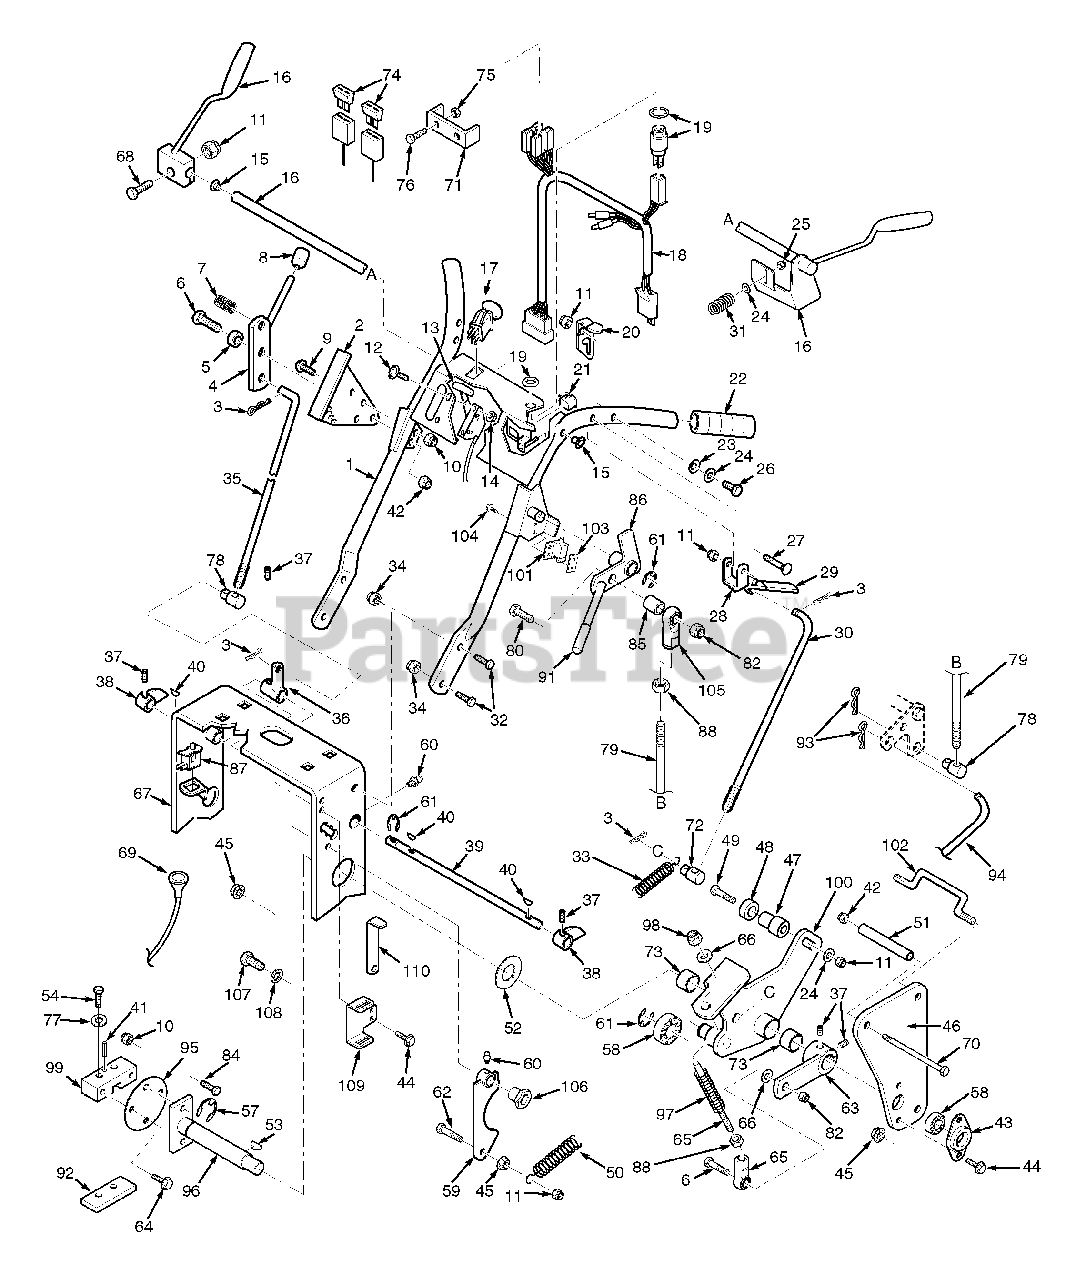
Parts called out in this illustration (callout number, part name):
1	Upper Handle Wlmt. W/Decals
2	Quadrant, Speed Control
3	Hairpin, .094 x 1.19
4	Lever, Speed Adjustment
5	Bushing, Speed Adjustment Lever
6	Hex Head Bolt, 3/8-16 x 1-1/2"
7	Ball Plunger
8	Knob, Speed Adjustment
9	Capscrew, 1/4-20 x 3/4" FHHS
10	Nut, 1/4-20 Elastic Stop
11	Nut, 5/16-18 Elastic Stop
12	Screw, #10-32 x 1/2" PW HD
13	Throttle Control
14	Nut, #10-32 Serr. Flange
15	Bushing
16	Handle, Oper. Presence-RH
17	Switch,Elec.Clutch Eng.
18	Wire Harness, Electric Start
19	Key Switch, Electric Srt.
20	Neutral Latch-RH
21	Switch, Neutral Interlock
22	Grip
23	Washer, Curved Spring
24	Flat Washer
25	Nut, 5/16-18 Elastic Stop
26	Hex Head Bolt, 5/16-18 x 2"
27	Hex Hd. Bolt, 5/16-18 x 2-1/2"
28	Lever, Steering Control
29	Grip, Steering Control
30	Rod, Steering Control
31	Spring, Handle Return
32	Capscr., 3/8-16 x 1" Ser. Flange
33	Spring
34	Nut, 3/8-16 Serr. Flange
35	Rod Speed Control
36	Bellcrank, Speed Control
37	Setscrew, 1/4-28 x .25"
38	Cam, Speed Control
39	Jackshaft, Speed Control
40	Key, 1/8 x 1/2" Woodruff
41	Roll Pin, 3/16-.75
42	Nut, Elastic Stop 3/8-16
43	Flange, Bearing
44	Capscrew, 5/16-18 x 1" Serr. Flg.
45	Nut, 5/16-18 Serrated Flange
46	Plate, Side
47	Spacer, Neutral Bearing
48	Bearing, Speed Ctrl. Bellcrank
49	Hex Head Bolt, 5/16-18 x 1-3/4"
50	Spring, Return
51	Spacer, Side Plate
52	Flat Washer, .766 x 1.25 x .035
53	Key, Woodruff, 3/16 x 3/4"
54	Bolt, Hex Head, 1/4-20 x 1-1/4"
55	Bolt, Hex Head, 5/16-18 x 3/4"
56	Lock Washer, 5/16"
57	Clip, Retaining, 3/4" diameter
58	Bearing, Ball Neutral Return
59	Cam, Neutral
60	Grease Fitting, 1/4-28 UNF
61	Retaining Ring, 5/8"
62	Hex Head Bolt, 5/16-18 x 1"
63	Lever, Speed Control
64	Bolt, Hex Head 1/4-20 x 3/4"
65	Linkage Assembly
66	Flat Wshr., 15/16 x .3906 x 12 ga
67	Deck, Engine 20" Wide
68	Hex Head Bolt, 5/16-18 x 1-1/4"
69	Choke Control
70	Bolt, Hex Head 3/8-16 x 4-1/4"
71	Fuse Holder
72	Swivel Joint, Steering Rod
73	Bushing
74	Blade Fuse, 20A
75	Nut, #10-32 Elastic Stop
76	Screw, #10-32 x 1-1/2" Phillips
77	Lockwasher, 1/4"
78	Swivel Joint
79	Rod, Brake Lever
80	Hex Hd. Bolt, 3/8-16 x 2"
81	Soc. Hd. Capscrew, #8-32 x 1/2"
82	Nut, 3/8-16 Elastic Stop
83	Washer #8-.170 x .375 x .032
84	Bolt, 1/4-20 x 3/4"
85	Spacer
86	Parking Brake Lever with Grip
87	Switch, Safety
88	Nut, 3/8-24
89	Bushing, Bearing Retainer
90	Bearing, Neutral Lock
91	Grip, Parking Brake
92	Plate, Threaded
93	Hairpin, .094 x 1.62"
94	Rod, Lower Brake
95	Plate, Coupler
96	Shaft, Pump Control
97	Spring
98	Nut, 3/8-16 Elastic Stop
99	Block, Pump Control
100	Control, LH
101	Switch, Parking Brake
102	Rod, Offset
103	Plate, Threaded
104	Screw #10-32 Sltd Hex Wshr Hd
105	Ball Joint, RH Thread
106	Bushing, Brake
107	Bolt, Hex Head 3/8-16 x 1"
108	Lockwasher, 3/8 Spring
109	Mounting Bracket, Wrench
110	Wrench
